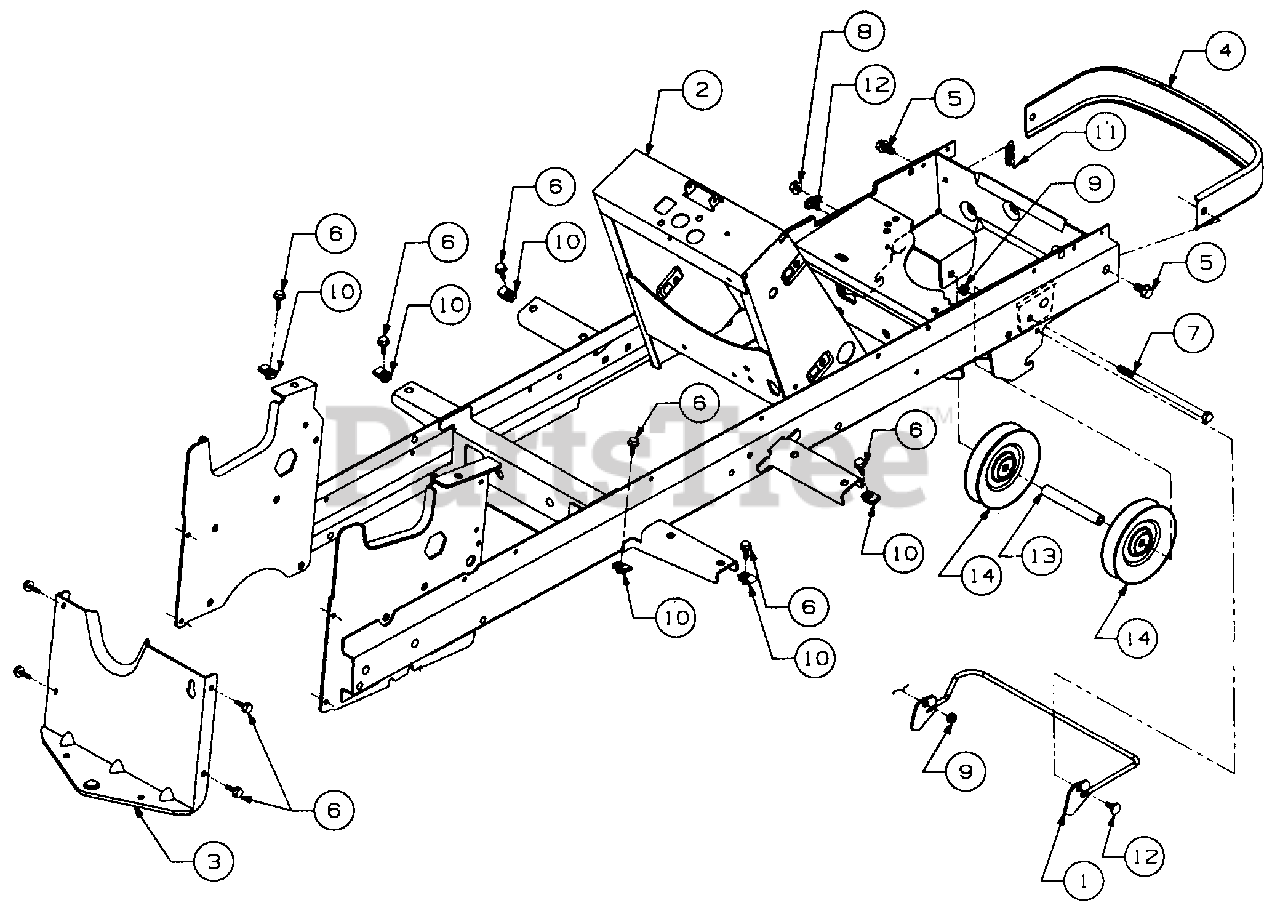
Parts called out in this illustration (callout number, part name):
2	Frame
6	Screw, Hex Wash Hd Tapp 5/16-18 x .75
7	Screw, Hex Cap, 3/8-16 x 7.0
8	Nut, Hex Flanged Lock, 3/8-16
9	Nut, Hex Flange Lock, 1/4-20
10	U-Nut, 5/16-18
11	Spring, Latch
12	Bolt, Shoulder
13	Spacer, Idler, .407 x .62 x 4.38
14	Pulley, Idler
